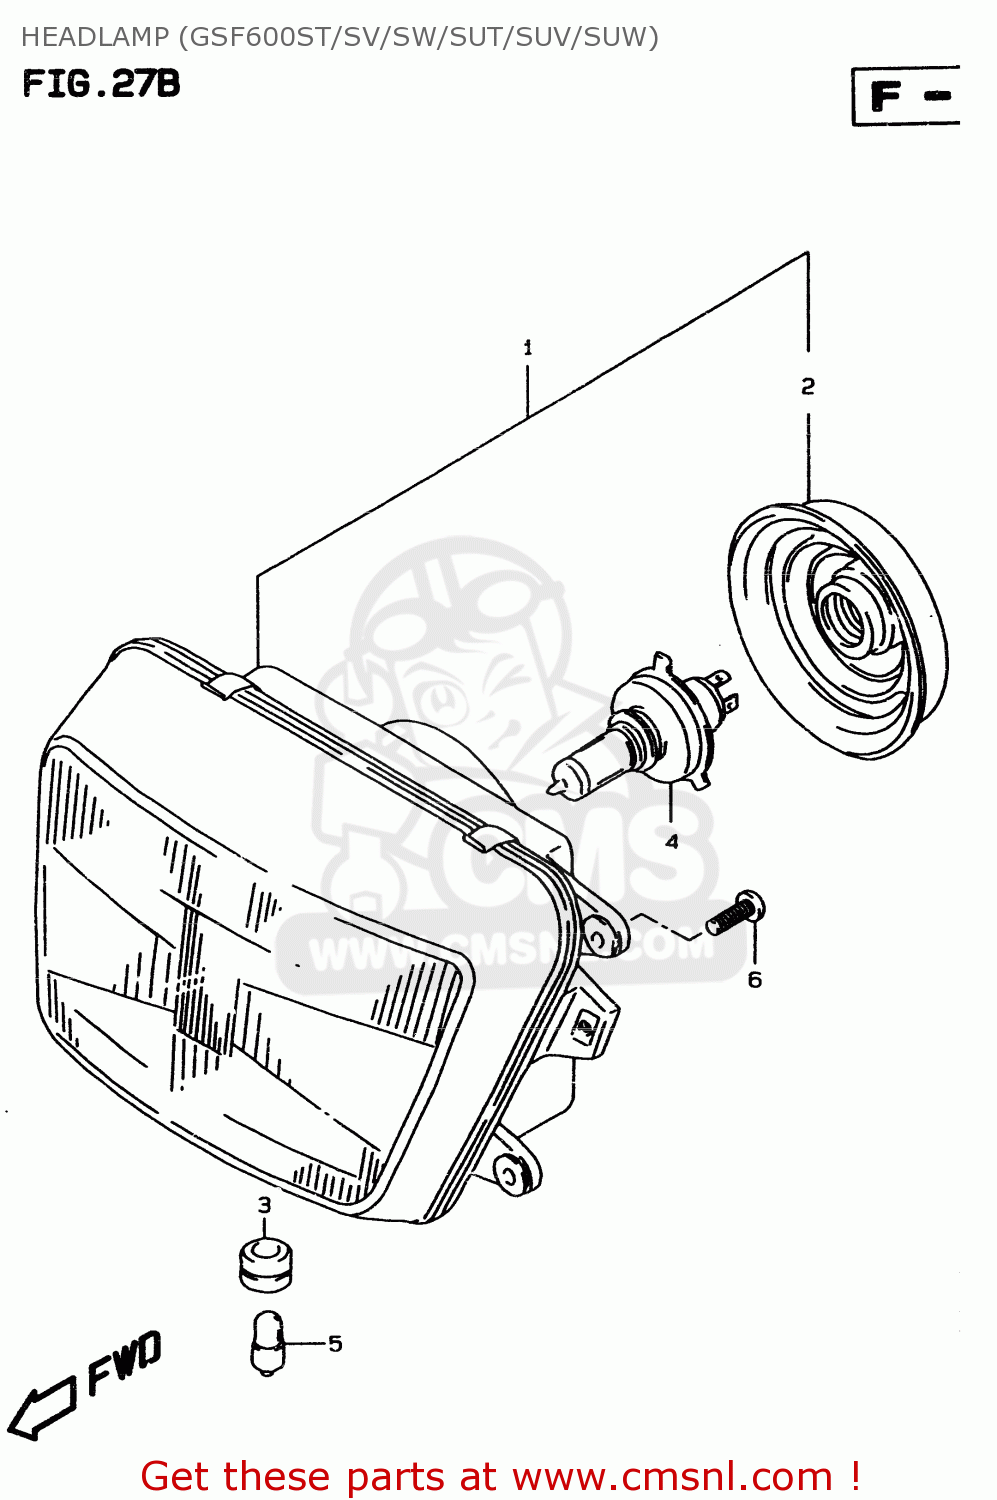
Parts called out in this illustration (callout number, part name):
1	HEADLAMP ASSY
2	COVER,SOCKET
3	JOINT,RUBBER
4	BULB(12V60/55W,H4)
5	BULB(12V4W)
6	SCREW
